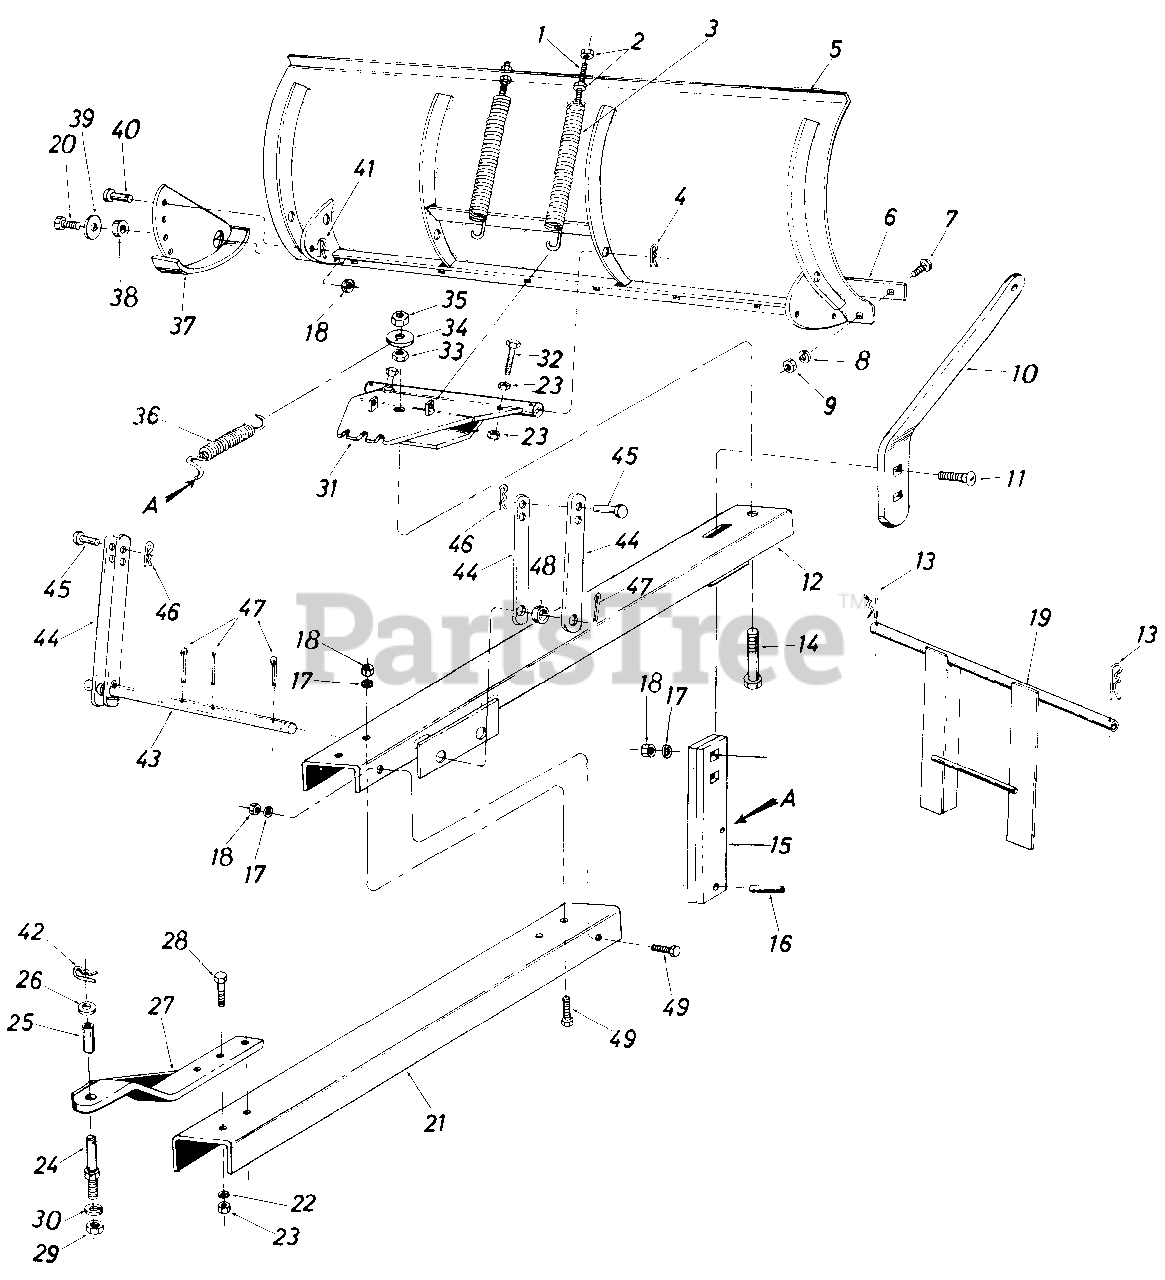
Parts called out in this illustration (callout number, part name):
1	Hex Scr. 3/8-16 x 4.50" Lg.*
2	Hex Nut 3/8-16 Thd.*
3	Blade Adjustment Spring
4	Hair Pin Cotter, 5/32
5	54" Blade Ass'y.
6	Wear Plate
7	Carriage Bolt 5/16-18 x .75" Lg.*
8	L.-Wash. 5/16" Scr.*
9	Hex Nut 5/16-18 Thd.*
10	Lock Extension Bar
11	Carriage Bolt 3/8-16 x 1.25" Lg.*
12	Front Push Bar Ass'y.
13	Hair Pin Cotter, 5/32
14	Hex Scr. 3/4-10 x 3.50" Lg.*
15	Angle- Lock Bar
16	Spring Pin Spirol .25" Dia. x 1.00" Lg.
17	L.-Wash . 3/8" Scr. *
18	Hex L.-Nut 3/8-16 Thd.*
19	Guide Bracket Ass'y.
20	Hex Scr. 3/8-16 x .75" Lg.*
21	Rear Push Bar Channel
22	L.-Wash. 1/2" Scr.*
23	Hex Nut 1/2-13 Thd.*
24	Link Clevis Pin
25	Spacer 1" O.D. x 21/32" I.D. x .75" Lg.
26	Fl-Wash. 21/32 I.D. x .090 O.D.
29	Hex Jam L.-Nut 5/8-18 Thd.
30	L.-Wash. 5/8" Scr.*
31	Pivot Plate Ass'y.
32	Hex Scr. 1/2-13 x 2.00" Lg.*
33	Hex Jam Nut 3/4-10 Thd.
34	Fl.-Wash. 3/8"
35	Hex Lock Nut 3/4-10 Thd.
36	Angle Lock Spring
37	Skid Assembly
38	Bushing, Pivot Skid
39	Fl.-Wash. .385" I.D. x 1.00" O.D.
40	Clevis Pin 5/16" Dia. x 3/4" Lg.
41	Hair Pin Cotter 3/32"
42	Hair Pin Cotter, 5/32
43	Lift Shaft
44	Lift Link
45	Clevis Pin 1/2" Dia. x 1.00" Lg.
46	HairPin Cotter, 3/32"
47	Cotter Pin 1/8" Dia. x 1.50." Lg.*
48	Spacer, Lift Link
49	Hex Scr. 3/8-16 x 1.00" Lg.*
